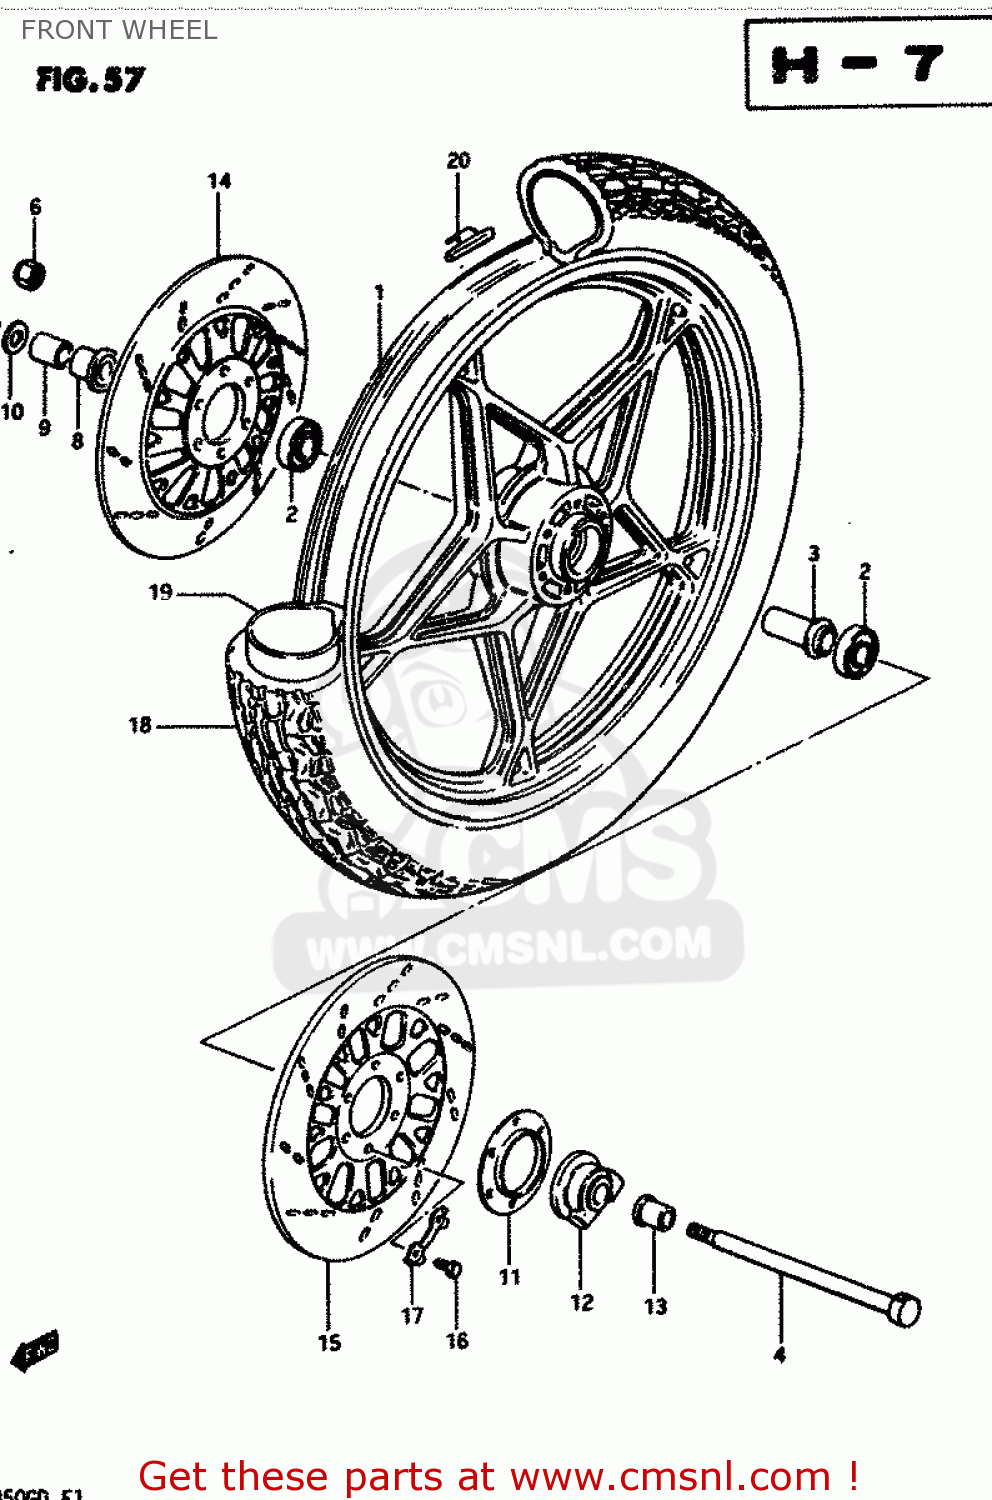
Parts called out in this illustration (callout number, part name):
1	CASTING WHEEL,FRONT 2.15
2	BEARING
3	SPACER,FR HUB BEARING
4	AXLE,FR
5	NUT 12MM
6	NUT
7	COTTER PIN
8	SPACER,FR AXLE,R
9	SPACER,FR AXLE,R
10	WASHER
11	DUST SEAL,SPEEDOMETER GEAR BOX
12	BOX ASSEMBLY,SPEEDOMETER GEAR
13	SPACER,FR AXLE,L
14	DISC,FR BRAKE,R
15	DISC,FR BRAKE,L
16	BOLT(8X25)
17	WASHER
18	TIRE,FRONT
19	TUBE,INNER
20	BALANCER,WHEEL
